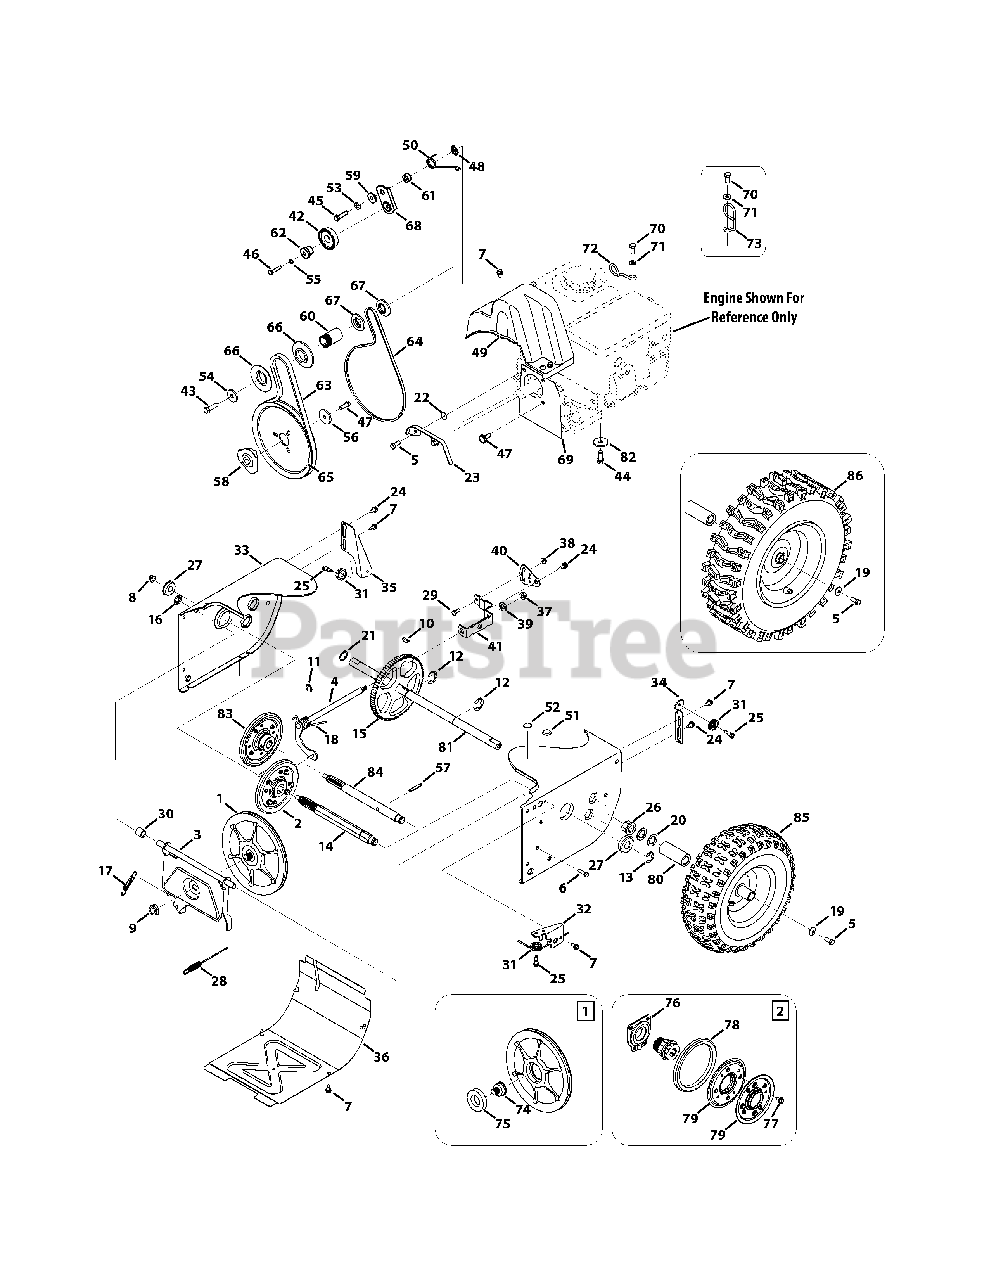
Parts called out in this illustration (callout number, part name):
1	Disc Assembly, Friction Wheel
2	Friction Wheel Assembly, 5.5 OD
4	Rod Shift Assembly
5	Hex Head Screw, 5/16-24 x .750
6	Taptite Screw, 1/4-20 x 1.000
7	Taptite Screw, 1/4-20 x .625
8	Flange Lock Nut, 3/8-16
9	Flange Nut, 5/8-18
10	Hi-pro Key, 3/16 x 3/4 Dia.
12	Retaining E-Ring, .875 Dia.
13	E-Ring, .750 Dia.
14	Hex Shaft, 7-Tooth
15	Gear, 80-Tooth
16	Speed Nut, .500
17	Extension Spring
18	Torsion Spring, .750 x .968
19	Bell Washer, .340 x .872 x .060
20	Flat Washer, .793 x 1.24 x .060
21	Flat Washer, .75 x 1.00 x .060
22	Washer, Flat, .385 x .62 x .063
23	Belt Cover
24	Shoulder Screw, .368 x .113, 1/4-20
25	Shoulder Screw, 1/4-28, .340 x .355
26	Hex Flange Bearing
27	Ball Bearing, 17 x 40 x 12
28	Wheel Clutch Cable, 44.95"
29	Hex Head Screw, 1/4-20 x .620
30	Spacer, .508 ID x .75 OD x .68
31	Cable Roller
32	Auger Cable Front Guide Bracket
33	Frame
34	Auger Cable Guide Bracket
35	Drive Cable Guide Bracket
37	Flange Lock Nut, 5/16-18
38	Flange Lock Nut, 1/4-20
39	Washer, Flat, .469 x .875 x .105
40	Speed Selector Pivot Bracket
41	Speed Selector Shift Bracket
42	Idler Pulley Assembly
43	Hex Screw, 3/8-24 x 1.25
44	Sems Screw, 3/8-16 x 1.00
45	Hex Screw, 5/16-24 x 1.25
46	Hex Screw, 1/4-20 x 1.25
47	Shoulder Screw, 5/16-24 x .5
48	Push-on Nut, .25 Dia.
49	Belt Cover 4-Way
49	Belt Cover
50	Torsion Spring, .850 ID x .333
51	Plug, 3/8 ID
52	Plug, 1/2 ID
53	Lock Washer, 5/16
54	Flat Washer, .406 x 1.25 x .157
55	Washer, Lock, 1/4
56	Flat Washer, .34 x 1.50 x .150
57	Pin, Spirol, 2.5"
58	Adapter Pulley, .75 Dia.
59	Shoulder Spacer, .3175 x .5 x .0975
60	Spacer, .875 ID x 1.185 OD
61	Spacer, .340 x .750 x .330
62	Shoulder Space, .260 x .785 x .538
63	Auger Drive Belt
64	Wheel Drive Belt
65	Auger Drive Pulley, 8.1 x .5
66	Pulley Half, 2.600 OD
67	Pulley Half, 3/8 x 1.716 OD
68	Wheel Drive Idler Bracket
69	Cover Plate
70	Hex Head Screw, 1.25 x 20
71	Washer, Flat, .330 x .630 x .0635
72	Cable Guide
73	Cable Guide
74	Friction Disc Bearing Pin
75	Ball Bearing, 30 x 55 x 13
76	Bearing Assembly
77	Screw, 1/4-14 x .625
78	Friction Wheel Rubber
79	Friction Wheel Plate
80	Spacer, 1.25 x .75 x 3.0
81	Axle, .75 x 22
82	Washer, Flat, .38 x 1.38 x .125
83	Friction Wheel Ass’y, Single-Speed
84	Shaft, Single-Speed
85	Snow Hog Wheel, 13 x 4 x 6
86	X-Trac Wheel, 13 x 4 x 6, LH
86	X-Trac Wheel, 13 x 4 x 6, RH
86	X-Trac Wheel, 16 x 4.8 x 8, LH
86	X-Trac Wheel, 16 x 4.8 x 8, RH
